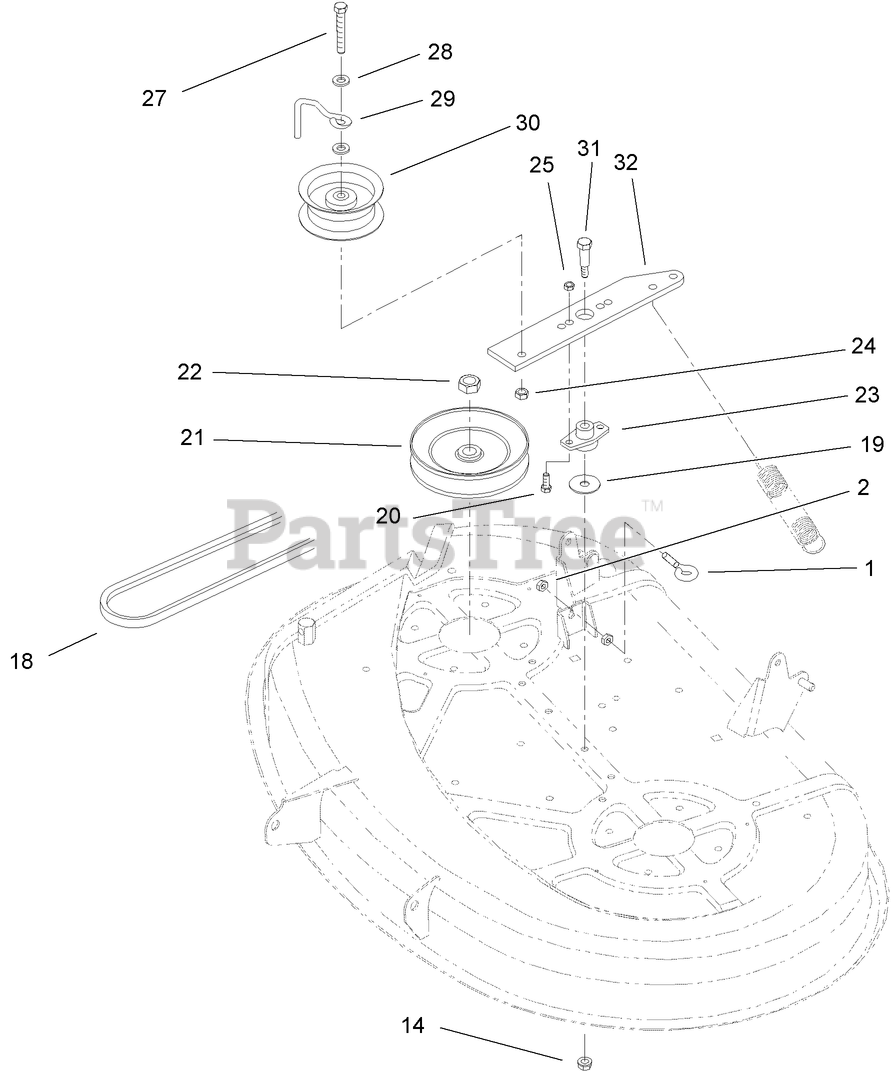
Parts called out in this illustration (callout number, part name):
1	EYEBOLT
2	NUT-JAM
14	NUT-LOCK, NI
18	V-BELT
19	WASHER-FLAT
20	SCREW-HH
21	PULLEY
22	NUT-HEX
23	BUSHING-ARM, IDLER
24	NUT-LOCK, NI
25	NUT-LOCK, NI
27	SCREW-HH
28	WASHER-FLAT
29	GUIDE-IDLER, BELT
31	SCREW-SHOULDER, HH
32	ARM-IDLER
